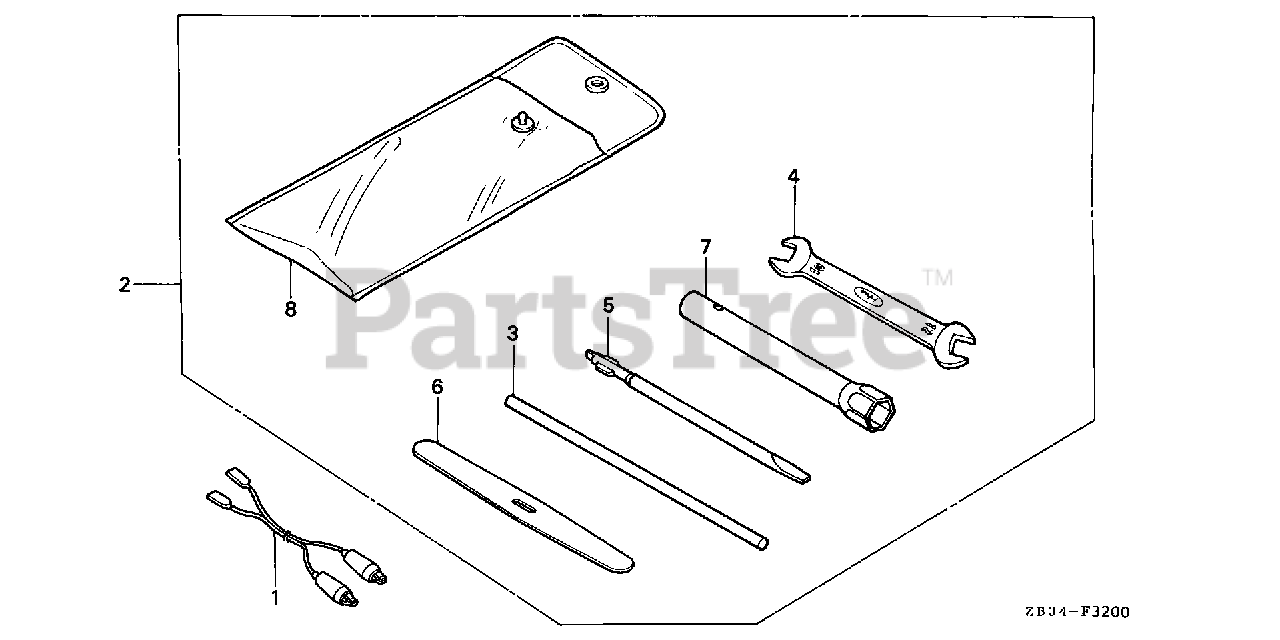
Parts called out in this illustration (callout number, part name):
2	TOOL KIT (NOT AVAILABLE)
3	BAR, PLUG WRENCH
4	SPANNER (10X12)
5	DRIVER 3, MINUS SCREW (NO.2)
6	LEVER
7	WRENCH, BOX (P21)
8	BAG, TOOL
